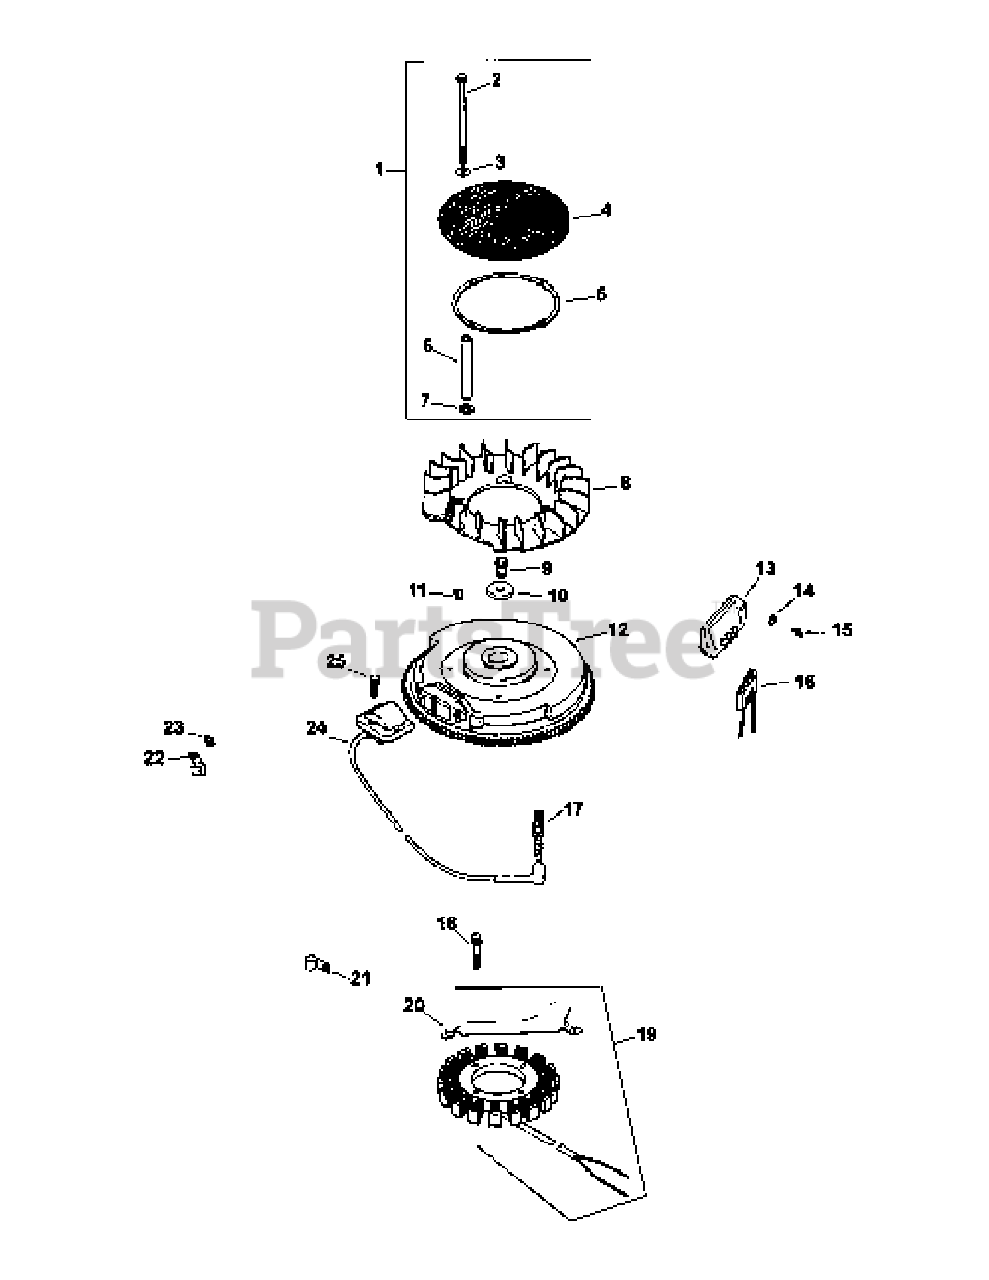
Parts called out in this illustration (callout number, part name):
1	Kit, Chopper Screen
2	Screw, Hex Flange M10x1.0x100
3	Washer, Plain 1/4"
4	Screen, Grass
5	Ring, Support
6	Spacer, Grass Screen
7	Washer, Spring 10 mm
8	Fan
9	Screw, Hex Flange M10x1.5x46
10	Washer, Plain 3/8"
13	Rectifier-Regulator
14	Washer, Plain 3/16"
15	Screw, Phillips hd. 11-16x7/8
16	Connector 3 contact
17	Spark Plug
18	Screw, Hex Cap M5x0.8x25
19	Kit, 15 Amp Stator
20	Bracket, Stator Wire
23	Washer, Plain 1/4"
24	Module, Ignition
25	Screw, Thread Forming M5x0.8x25
26	Screw Hex Flange M4x0.7x10
27	Module, Speed Advance
